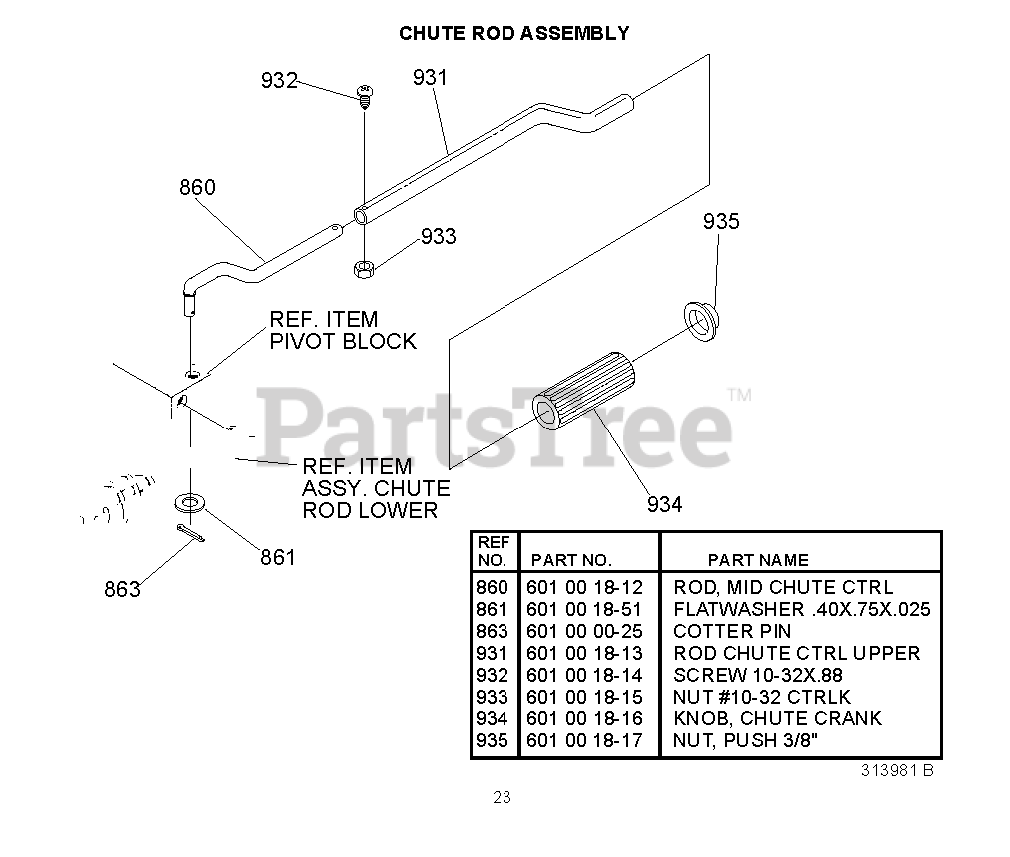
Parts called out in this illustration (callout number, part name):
860	ROD, MID CHUTE CTL
861	WASHER, FLAT .40X.75X.025
863	PIN, COTTER .090/.086X.75
931	ROD CHUTE CTRL UPR, ASSN
932	SCREW, 10-32 X .88 SLTRHD
933	NUT, #10-32 CTRLK
934	KNOB, CHUTE CRANK
935	NUT, PUSH, FTS 3/8 DIA
